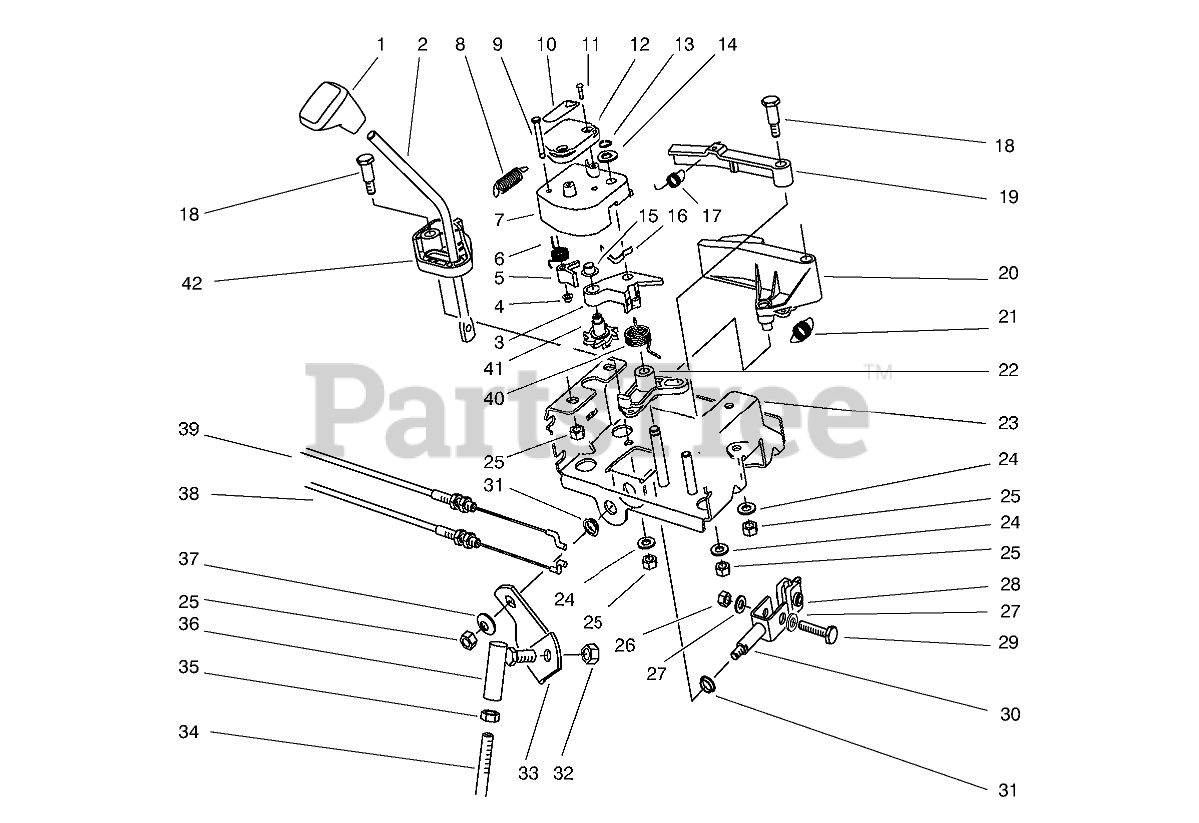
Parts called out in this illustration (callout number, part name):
1	KNOB-SHIFT
2	ROD-SHIFT
3	LEVER-WHEEL, INDEX
4	NUT-PUSH
5	TANG-INDEX
6	SPRING-TORSION
7	LATCH-LEVER
8	SPRING-EXTENSION
9	PIN-TANG
10	DECAL
11	SCREW
12	COVER-LATCH
13	RING-RETAINING
14	WASHER-THRUST
15	RETAINER-PUSH ON
16	SPRING-FLAT
17	SPRING-EXTENSION
18	SCREW-SHOULDER
19	LEVER-LOCKOUT
20	LEVER-REVERSE
21	SPRING-EXTENSION
22	LEVER-REVERSE, SWITCH
23	Frame-Control
24	WASHER-PLAIN
25	NUT-LOCK, NI
26	NUT-LOCK, NI
27	WASHER-FLAT
28	RETAINER-ROD, SHIFT
29	SCREW-HH
30	CLEVIS ASM
31	BUSHING
32	NUT-LOCK
33	BRACKET-SHIFT
34	ROD-BENT SHIFT, LOWER
35	NUT-HJ
36	BALL-JOINT
37	WASHER-BELLEVILLE
38	CABLE-GEARBOX
39	CABLE-ARM, LATCH
40	SPRING-TORSION
41	WHEEL-INDEX
42	BASE-LOCKOUT
